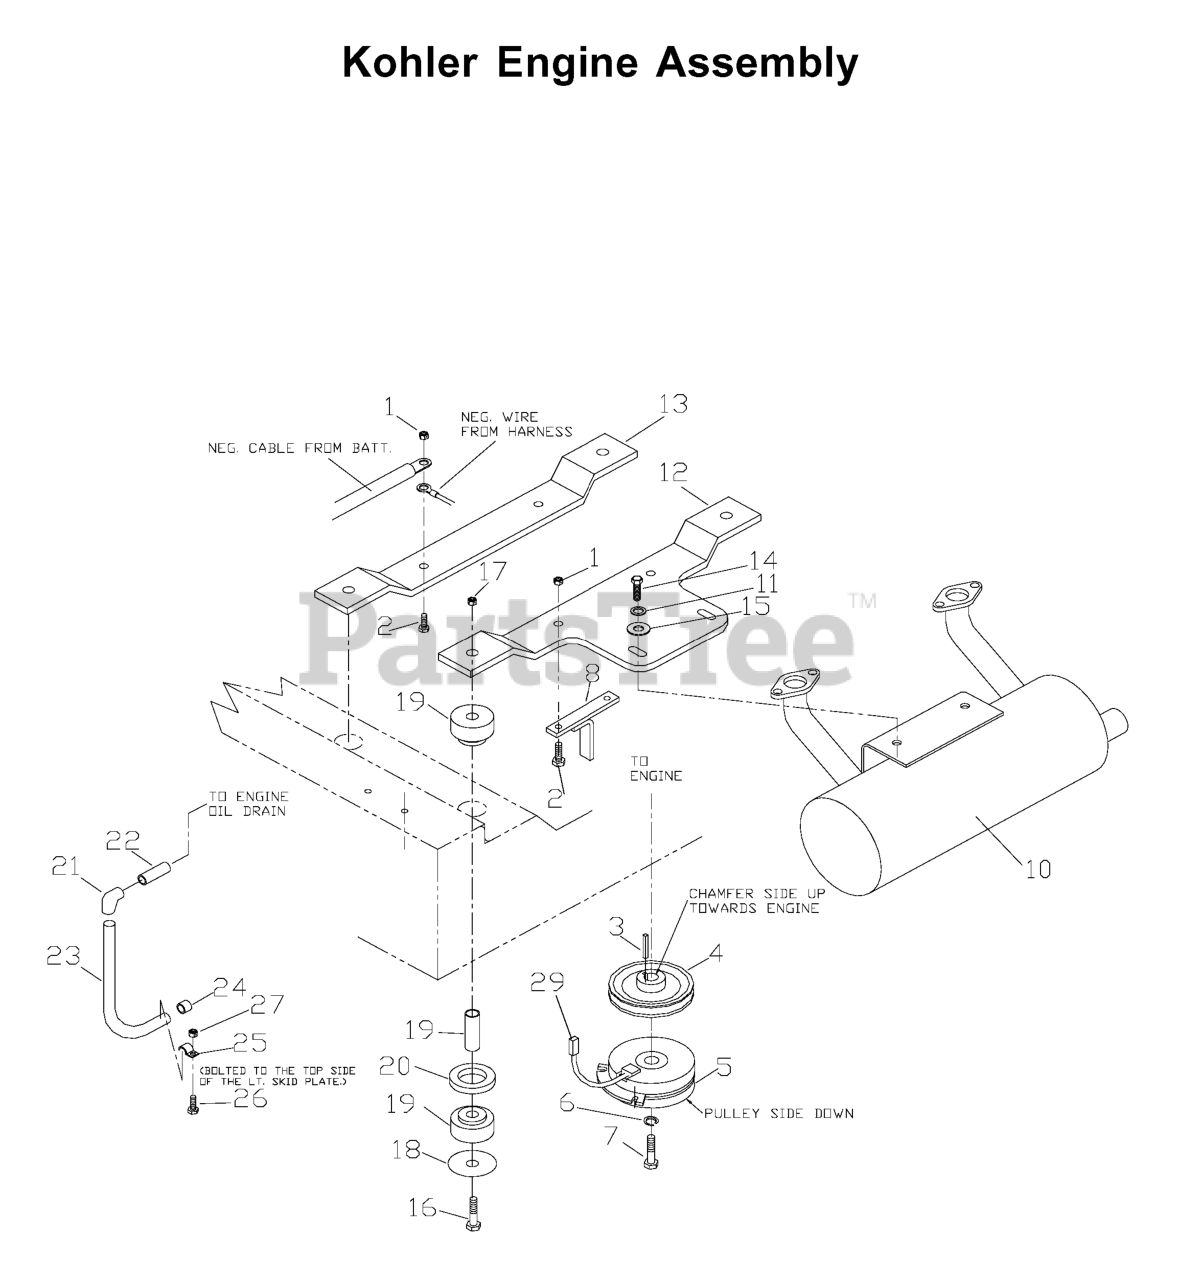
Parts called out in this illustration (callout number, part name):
1	NUT 5/16C CENTERLOCK
2	HCS 5/16C X 1 3/4
3	KEY 1/4" SQ X 1 7/8"
5	ELECTRIC CLUTCH W/CABLE
6	WASHER 7/16 LOCK
7	BOLT 7/16F X 2 1/2
8	CLUTCH TIE DOWN
9	KOH PIGTAIL
10	MUFFLER KOHLER GEN II
11	WASHER.LOCK.HVY.HLCL.SPR.5/16
12	REAR ENGINE MOUNT
13	ENGINE MOUNT
14	HCS 5/16C X 3/4
15	WASHER 5/16 FLAT
16	HCS 1/2C X 3 1/4
17	NUT 1/2-13 HEX NYLOC ZD
18	ISOLATOR WASHER
20	ISOLATOR SPACER
21	90 DEG.ELBOW 3/8NPT
22	PIPE 3/8 NPT 1-1/2
23	OIL DRAIN HOSE
26	HCS 1/4C X 3/4 HCS
27	NUT 1/4C CENTER LOCK
28	CHOKE CONTROL, COMPLETE
29	CLUTCH HARNESS
